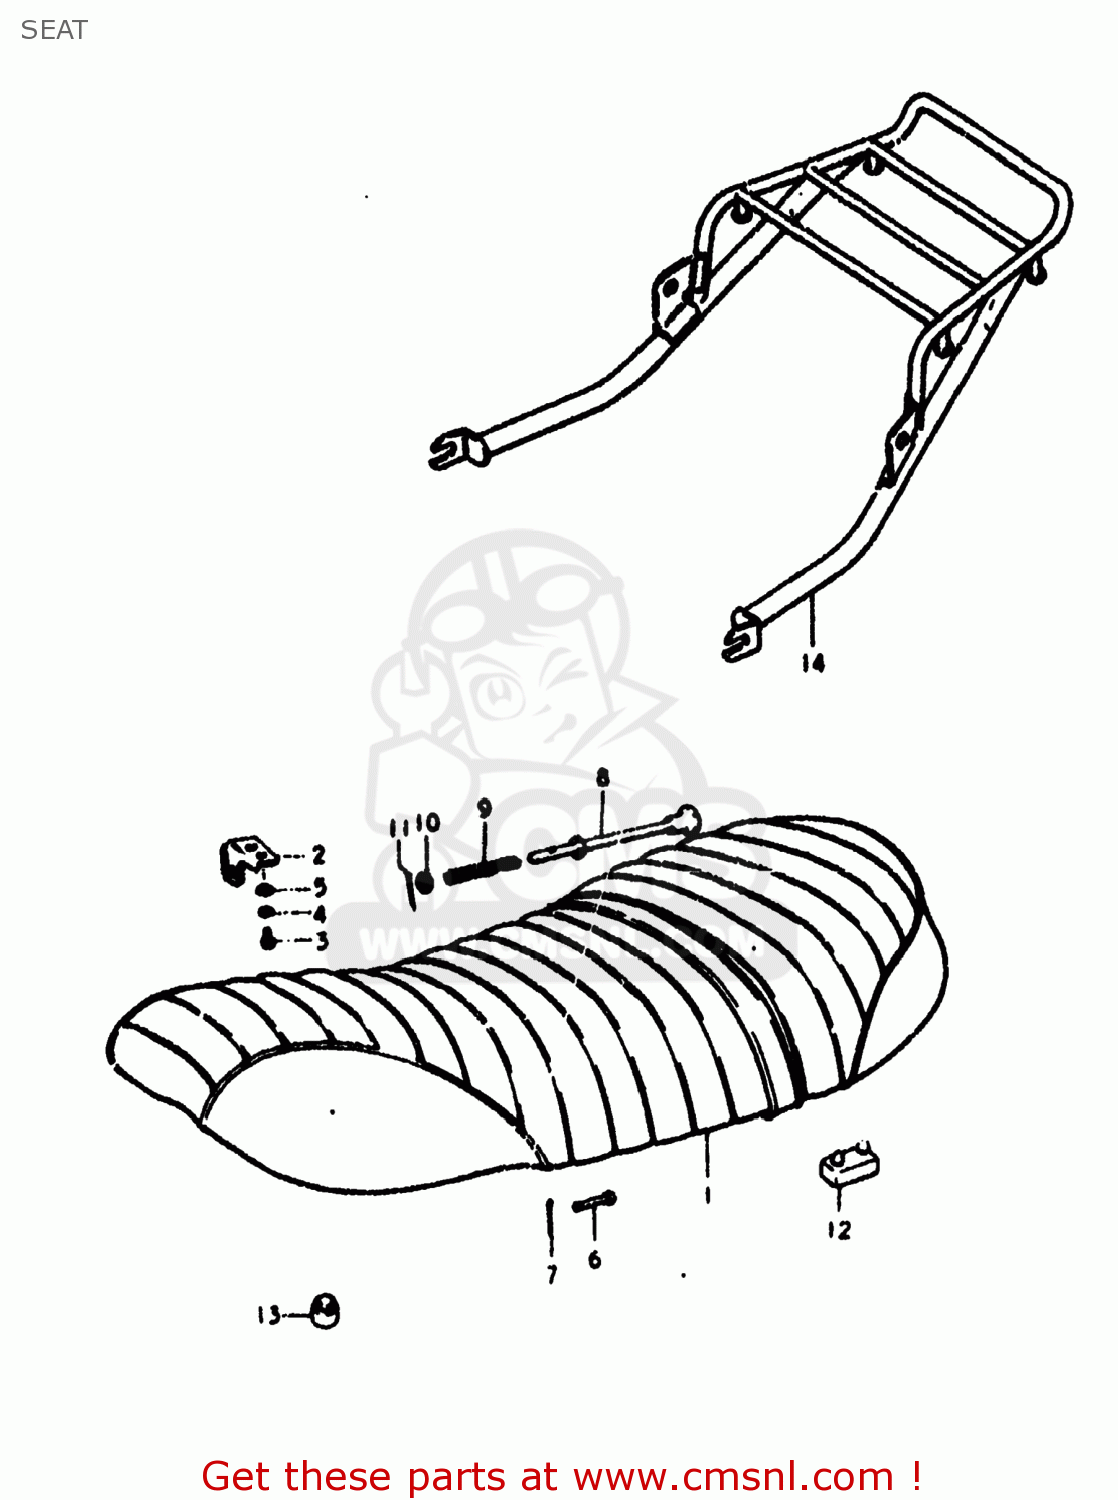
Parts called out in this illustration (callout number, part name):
1	SEAT ASSEMBLY
2	PLATE,CLUTCH GUIDE
3	BOLT
4	LOCK WASHER
5	WASHER
6	PIN
7	PIN
8	BAR,SEAT CLAMP
9	SPRING
10	WASHER
11	PIN 20X20
12	CUSHION
13	CUSHION
14	CARRIER
